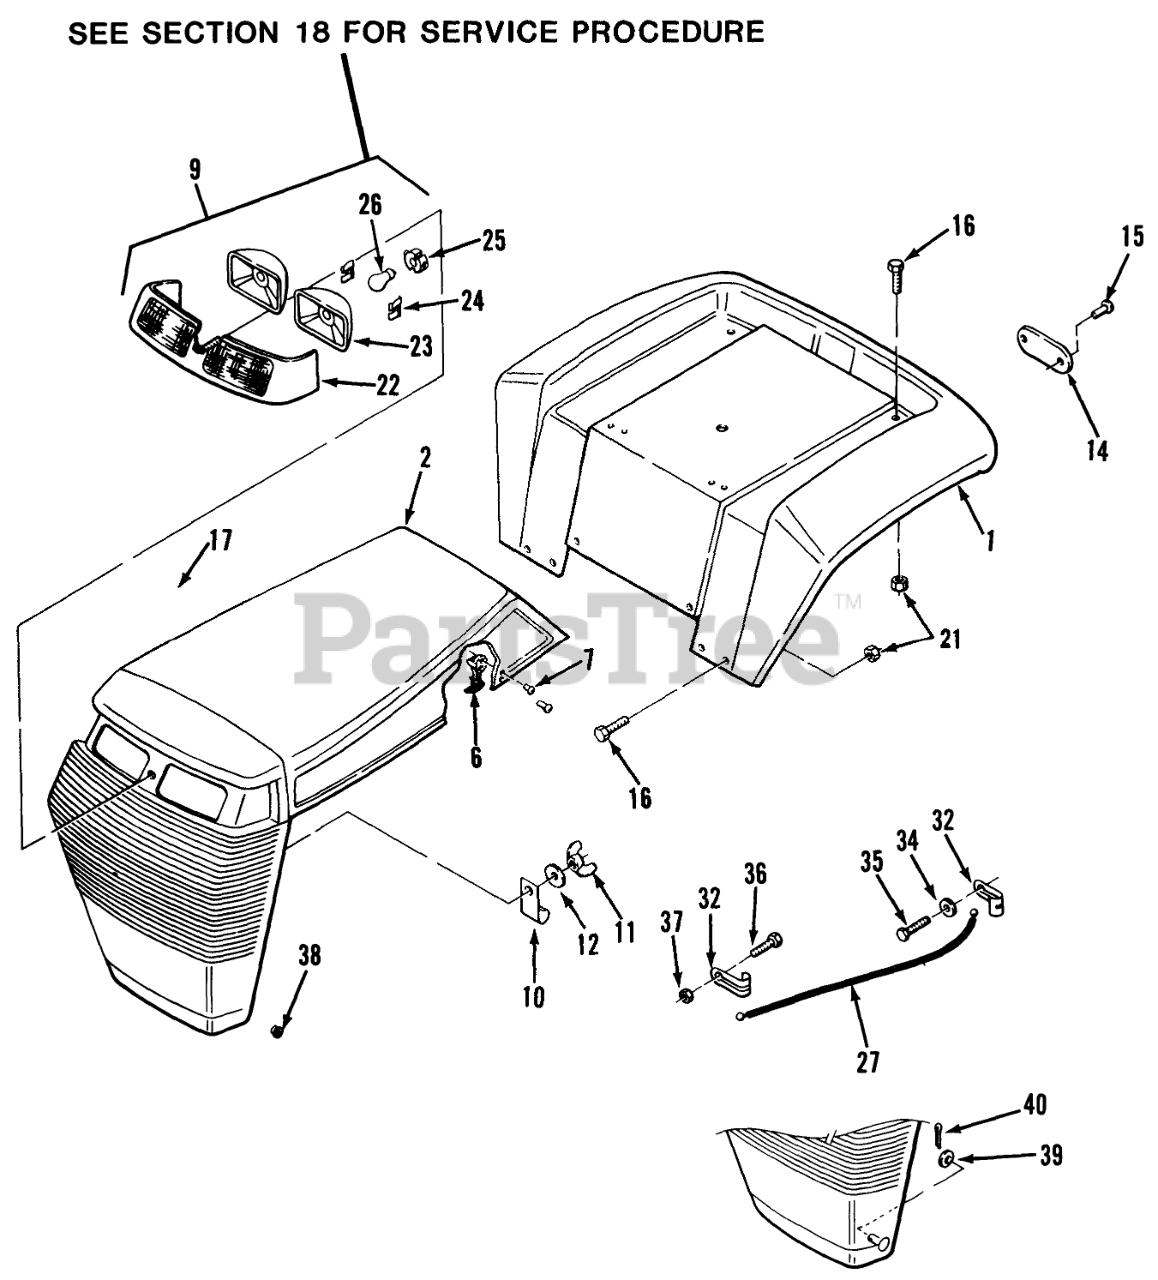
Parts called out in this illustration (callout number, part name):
1	FENDER R
2	Hood & Grill
6	KEEPER-LATCH
7	RIVET-POP
9	Head Light Bar (Includes items 22, 23, 24, 25 & (2) of 26)
10	J-CLIP
11	Nut-Wing
12	WASHER
14	Reflector
15	Poprivet
16	Bolt-Carriage
21	Nut
22	LIGHT-BAR BLACK
23	LIGHT POD
24	RETAINER
25	SOCKET-HEADLIGHT
26	BULB
27	CABLE-ASS'Y
32	CLEVIS
34	Washer
35	Bolt
36	Screw-Machine
37	Nut
38	NYLINER BUSHING
39	WASHER 5/16 SAE
40	Cotter Pin
